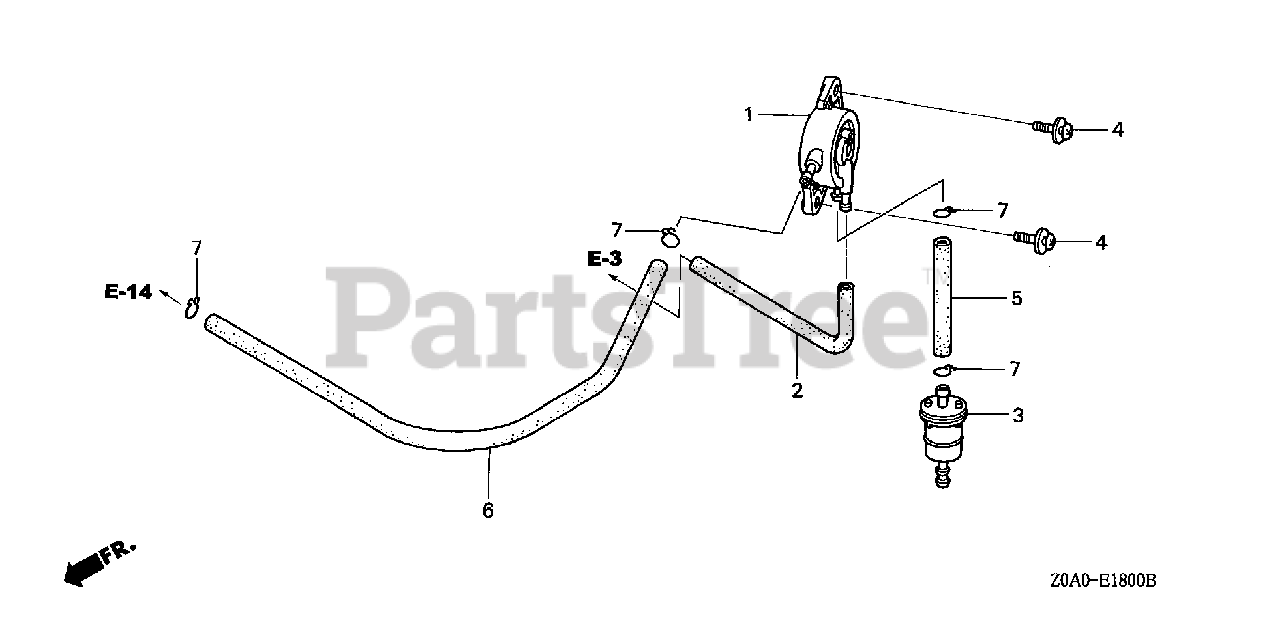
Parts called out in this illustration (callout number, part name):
1	PUMP ASSY., FUEL
2	TUBE, DIAPHRAGM
3	STRAINER, FUEL
4	SCREW-WASHER (5X16)
5	BULK HOSE, FUEL (5.5X3000) (5.3X100)
6	BULK HOSE, FUEL (5.5X3000) (5.3X350)
7	CLIP, TUBE (B10)
